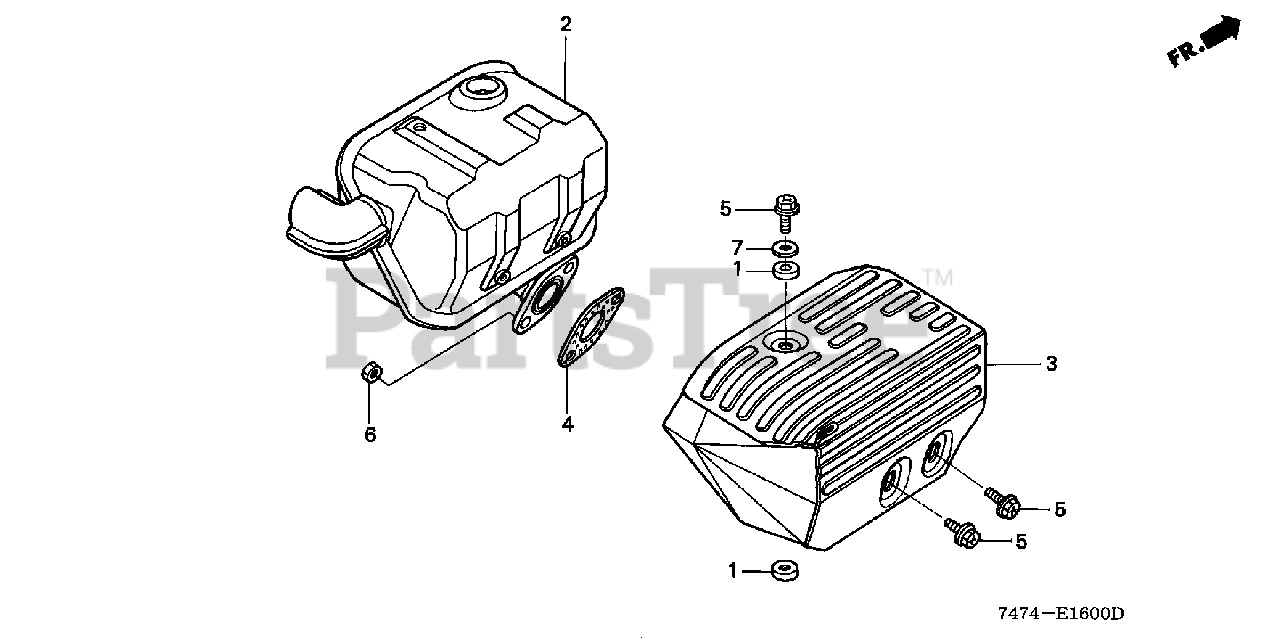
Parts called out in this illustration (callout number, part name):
1	GASKET, PROTECTOR
3	COVER, MUFFLER
4	GASKET, MUFFLER
5	SCREW, TAPPING (5X14)
6	NUT, HEX. (8MM)
7	WASHER, PLAIN (6MM)
